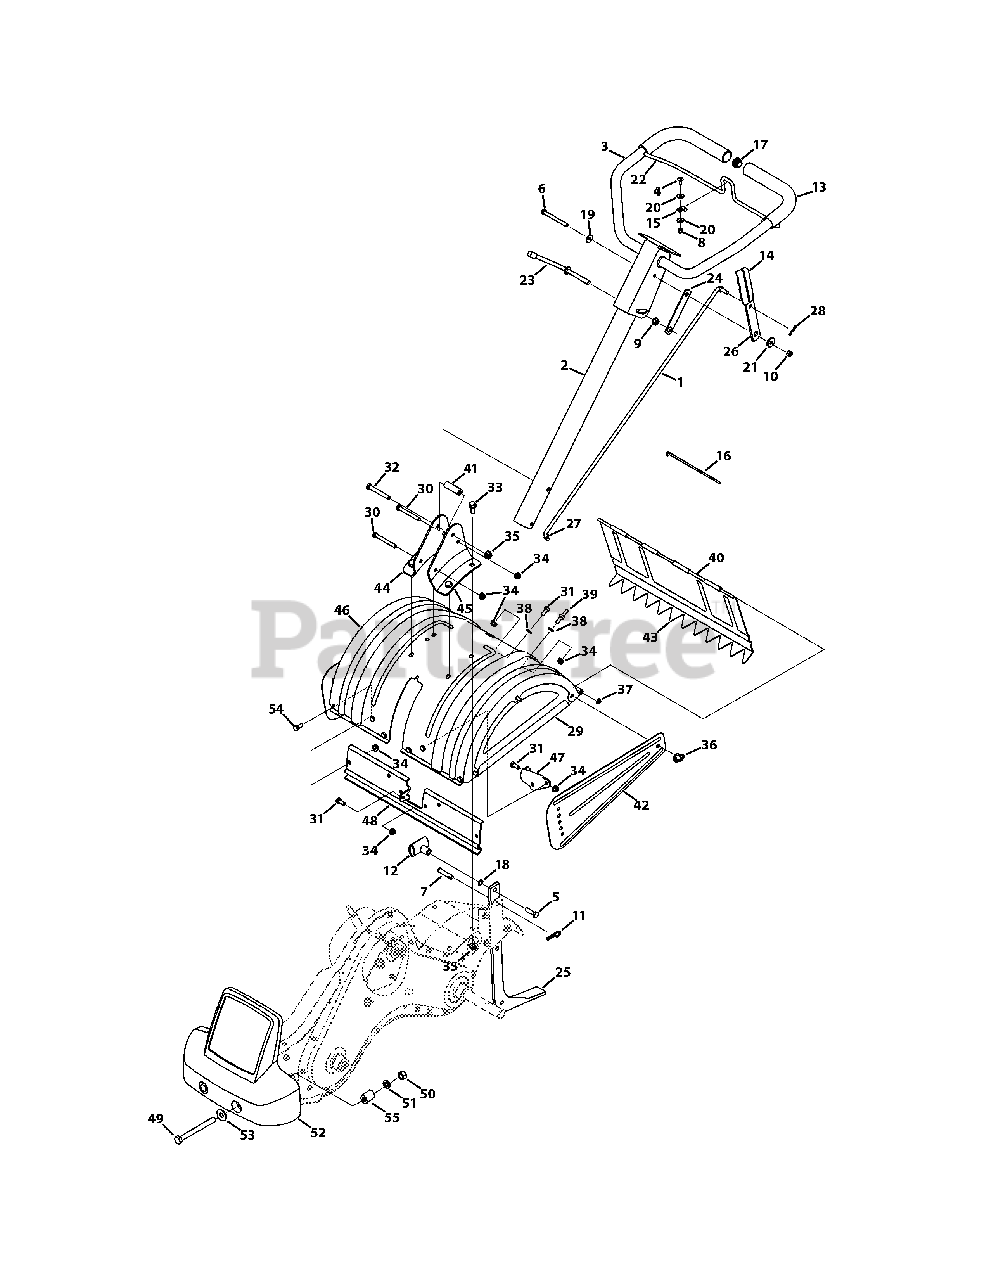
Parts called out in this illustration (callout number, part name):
1	Shift Rod
2	Lower Handle Tube Assembly
3	Upper Handle Assembly
4	Screw, 1/4-20 x 0.625
5	Hex Head Screw, 3/8-16:1.25
6	Hex Head Screw, 5/16-18 x 3.25
7	Clevis Pin, .375 X 1.75
8	Hexlock Nut, 1/4-20
9	Flangelock Nut, 3/8-24
10	Hexlock Nut, 5/16-18
11	Cotter Pin, .125 X 1.75 Internal
12	Small Tee Knob
13	Foam Grip, .970 x 11.0
14	Grip, .1875 x 1.00
15	Battery Clamp, 5/16
16	Cable Tie, 8.5 LG
17	End Plug
18	Washer, Flat, .385 x .620 x .033
19	Washer, Bell, .340 x .872 x .060
20	Washer, Flat, .260 x .720 x .060
21	Spacer, .50 x .190 x .360 LG
22	Clutch Bail
23	Handle Adjustment Crank
24	Hex Nut Retainer Bracket
25	Tiller Depth Control
26	Shaft Rod Lever
27	Washer, .33 ID x .87 OD x .125
28	Cotter Pin, .072 x 1.12 LG
29	End Cover Assembly
30	Hex Head Screw, 5/16-18 x 2.75
31	Hex Head Screw, 5/16-18 x .75
32	Hex Head Screw, 3/8-16 x 2.75
33	Hex Head Flange, 3/8-16 x .875
34	Flangelock Nut, 5/16-18
35	Flangelock Nut, 3/8-16
36	Wing Nut, 5/16-18 W/ Bell Washer
37	Speed Nut Cap, 1/4 ROD
38	Washer, Flat, .344 x .62 x .033
39	Screw, Hex, 5/16-18 x .75
40	Tiller Flap Rod
41	Spacer, .322 x .625 x 2.00
42	Side Shield
43	Rear Tine Shield
44	RH Handle Mount Bracket
45	LH Handle Mount Bracket
46	Tine Shield
47	FRT Tine Shield Bracket
48	FRT Tine Shield Spacer Bracket
49	Hex Head Screw, 1/2-20 x 5.50
50	Hex Nut, 1/2-20
51	Washer, Lock, 1/2
52	Counterweight
53	Washer, Flat, 1/2 x 1.25 x .100
54	Hex Head Screw, 5/16-18 x 1.00
55	Hub, .636 ID x 1.00 OD x .94
